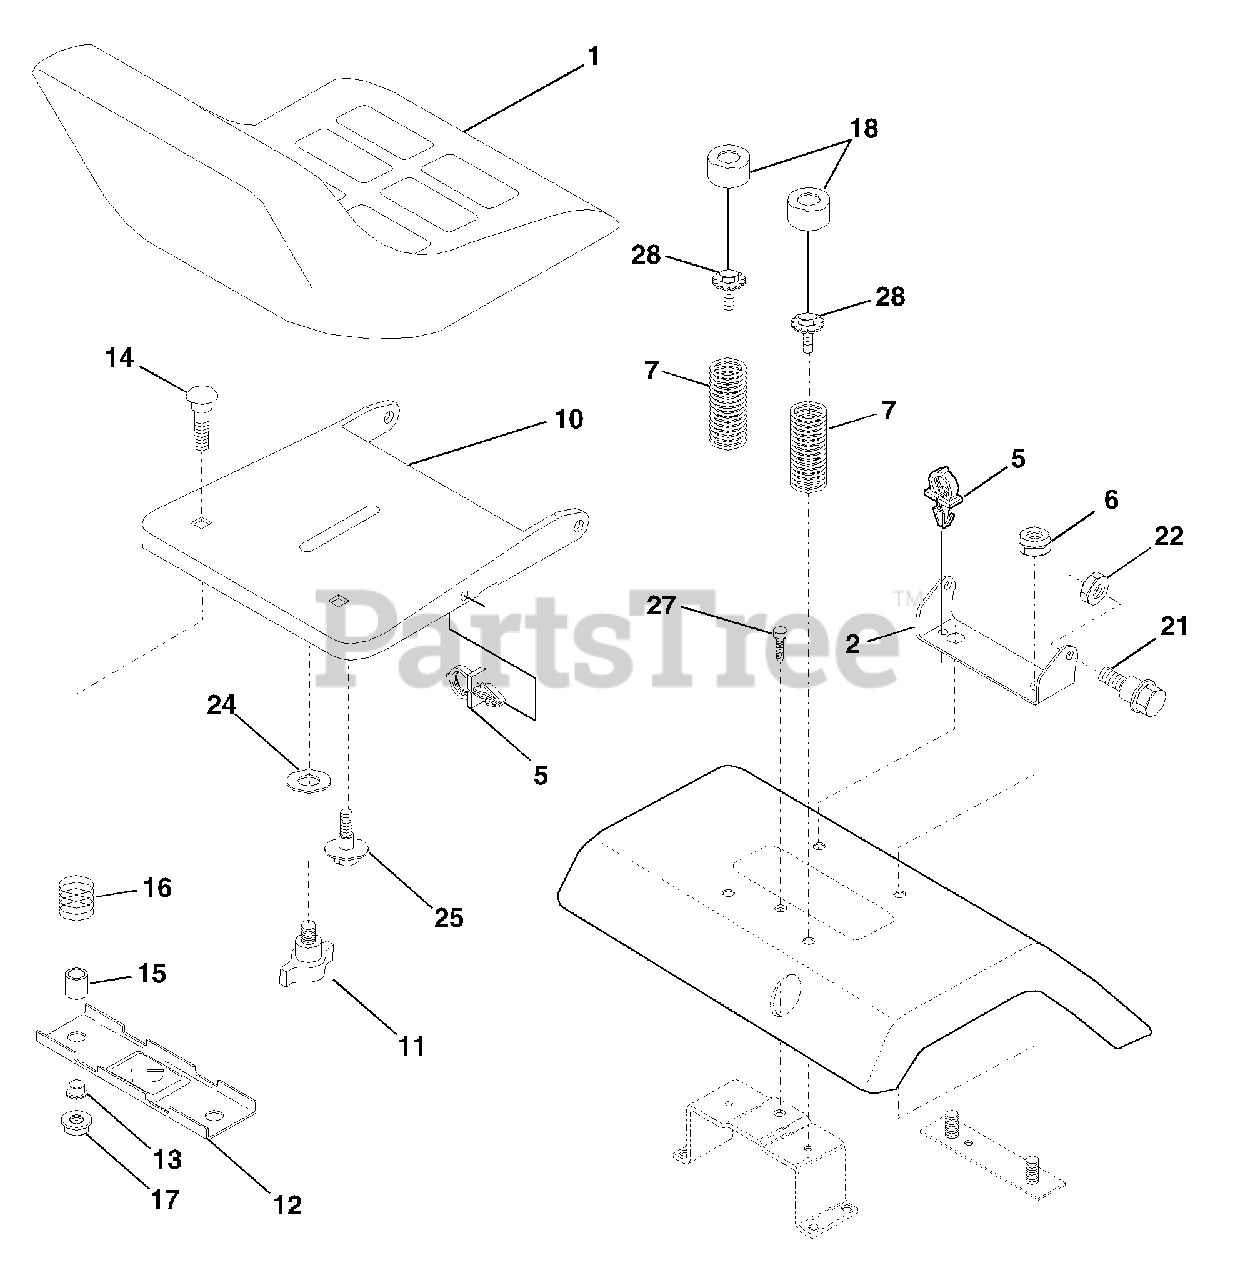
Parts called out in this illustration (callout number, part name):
1	Seat
2	Pivot Bracket, Seat
5	Clip, Push-in Hinged
6	Nut, Lock Hex w/Ins 3/8-16 UNC
7	Spring, Seat
10	Pan, Seat
11	Knob, Seat
12	Bracket, Switch Mounting
13	Bushing, Snap, Black, Nylon
14	Bolt, Carriage 1/4-20 x 1-1/2
15	Spacer, Split .28 x .96
17	Locknut, Flange 1/4 Grade 5
18	Cap Spring Seat Blk 1.75 x 1.0
21	Bolt, Shoulder 5/16-18 Unc -2A
22	Nut, Crownlock 5/16-18
24	Washer 17/32 x 1-3/16 x 12 Gauge
25	Bolt, Shoulder 5/16-18 x .62
27	Screw Thdrol 3/8-16 x 3/4
28	Bolt 5/16-18 UNC x 3/4 w/Sems
